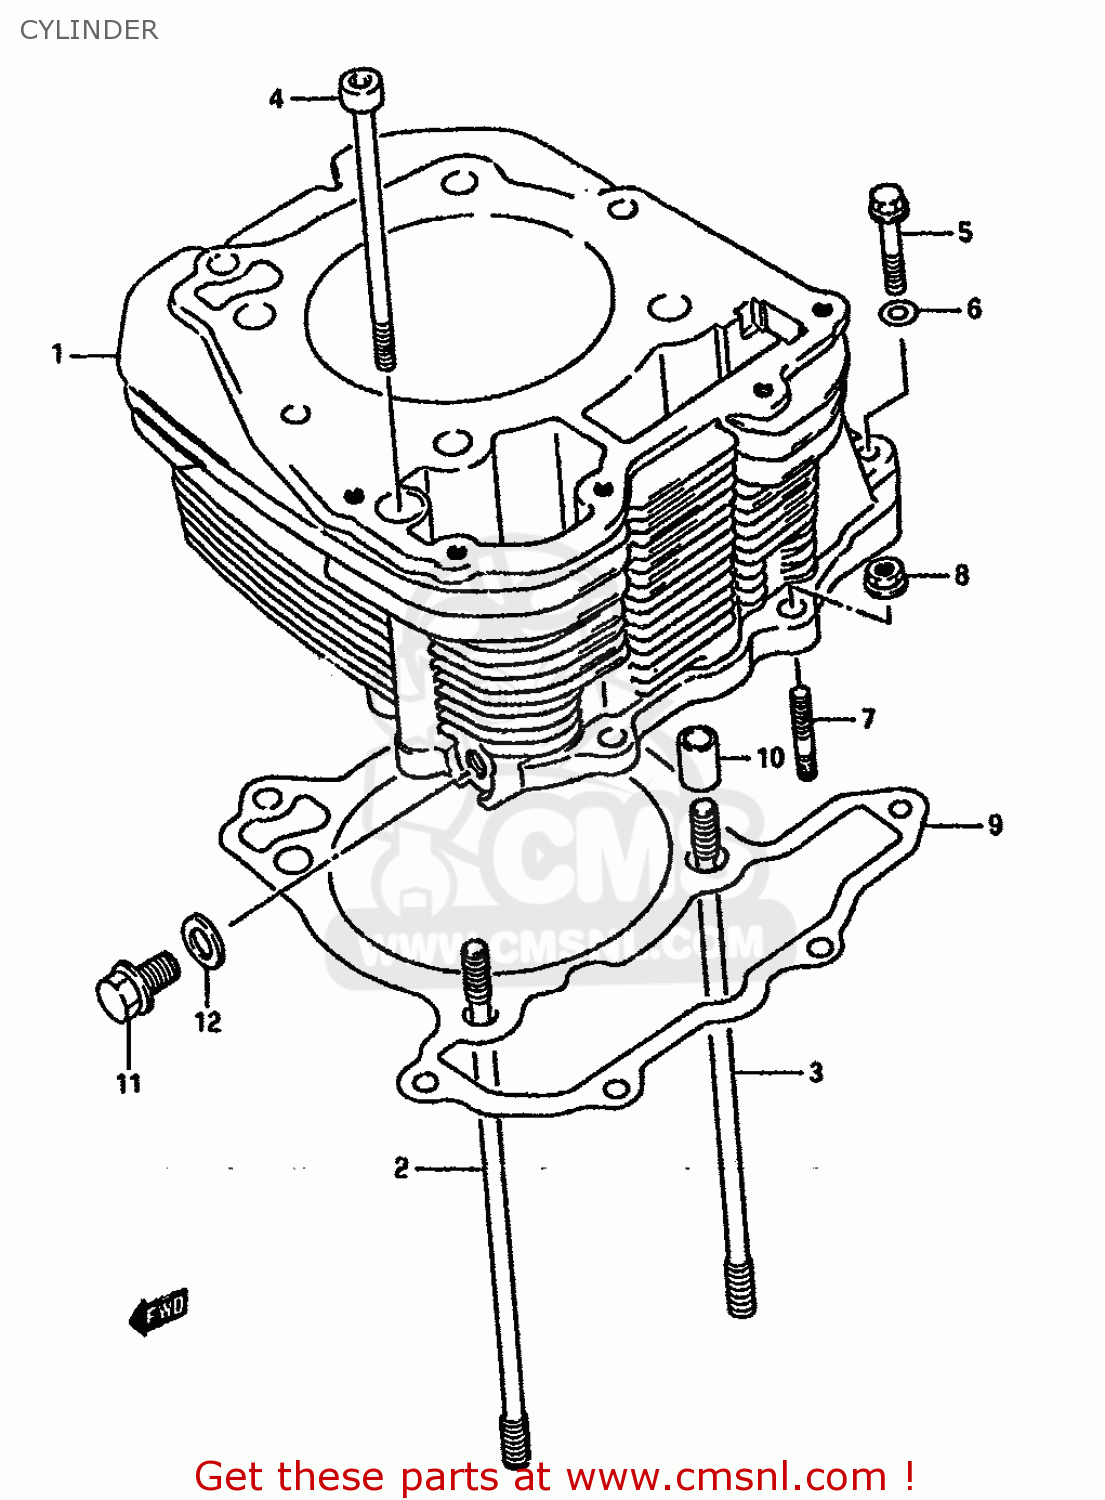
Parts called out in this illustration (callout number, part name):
1	CYLINDER (BLUE)
2	BOLT,STUD
3	BOLT,STUD(10X195)
4	BOLT L:115
5	BOLT
6	GASKET(5.8X13X1.2) (NAS)
7	STUD BOLT L:20
8	NUT 6MM
9	GASKET,CYLINDER (NAS)
10	PIN
11	BOLT
12	GASKET(10.2X20X2).3 (NAS)
